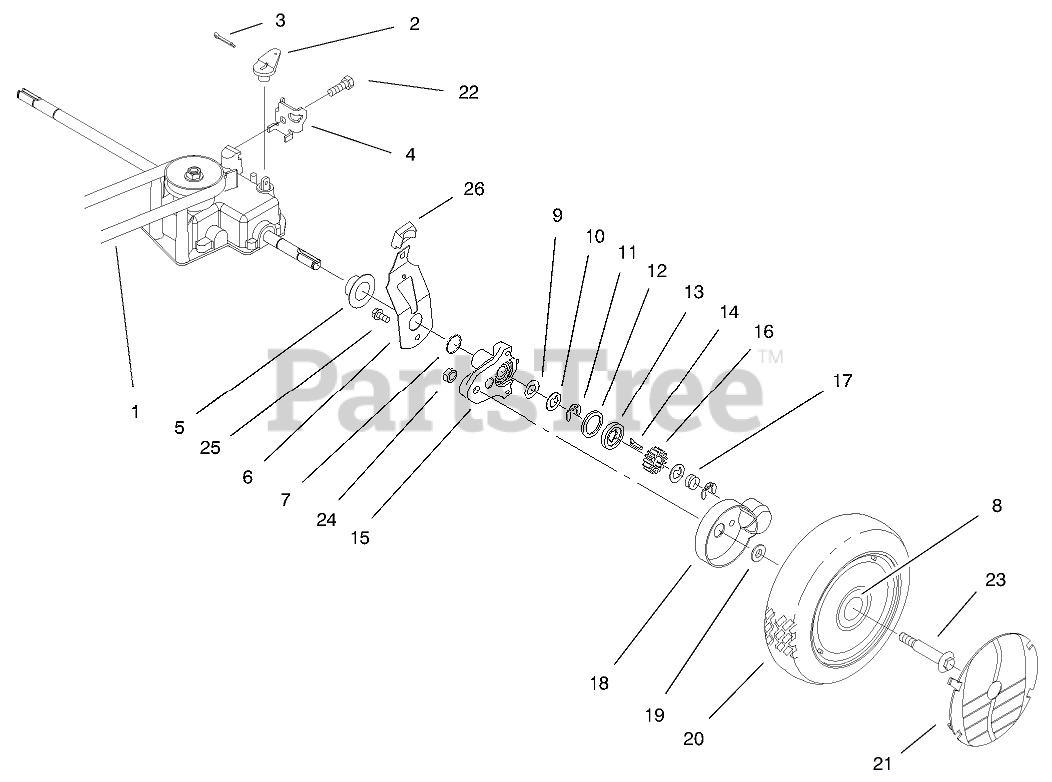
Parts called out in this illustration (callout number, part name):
1	V-BELT E
2	LEVER-SHIFT
3	PIN-COTTER
4	CLAMP-CABLE
5	CAP-END
6	SPRING ARM ASM
7	O-RING
8	BUSHING
9	WASHER-ARM, PIVOT
10	WASHER-THRUST, KEYED
11	RING-CLIP, LOCKING
12	RING-FRICTION
13	WASHER-CLUTCH
14	KEY-ROCKING, LH
15	ASM
16	GEAR-PINION
17	SPRING-COMPRESSION
18	COVER-WHEEL
19	SPACER-COVER, WHEEL
20	Wheel & Tire Assembly (Incl. Ref. #8)
21	WHEEL COVER
22	SCREW-HWHTF
23	BOLT-WHEEL
24	NUT-LOCK
25	SCREW-HWH
26	KNOB-ARM
